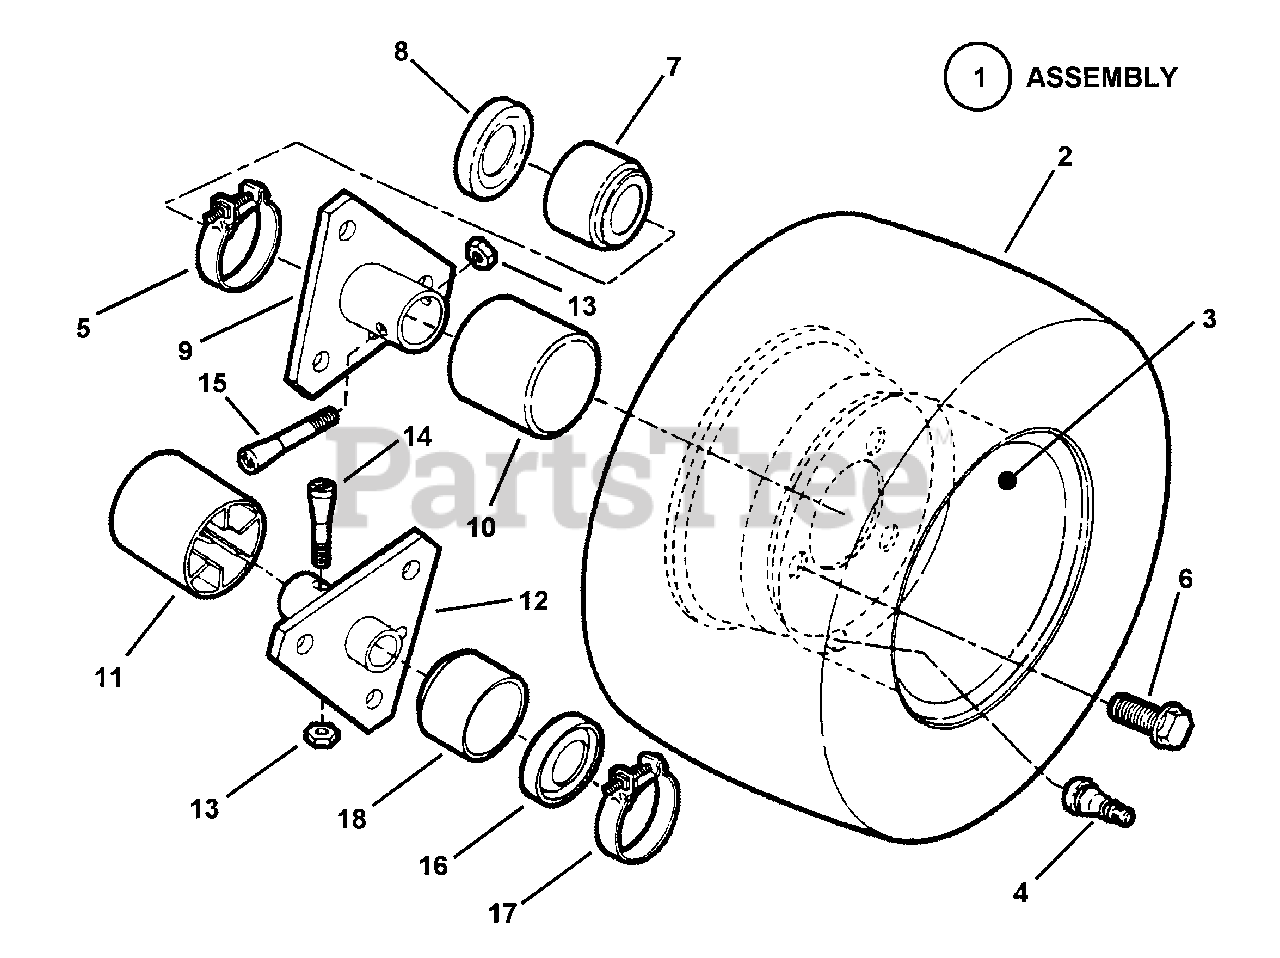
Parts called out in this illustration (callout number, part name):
1	ASSEMBLY, Rear Tire & Rim
2	TIRE, 16 x 6.50-8 (Kenda)
3	RIM, Ext. Wide,
4	VALVE, Air (Snap-in)
5	CLAMP, Right Hand (3.0" ID) (Right Hand)
6	BOLT, 1 /2-20 x 3/4" Lug (Grade 5)
7	CAP, Seal .93" ID x 2.625" OD (Right Hand)
8	SEAL, Oil 1.22" ID x 1.875" OD (Right Hand)
9	HUB, Wheel RH, 3 Hole 1" ID
10	CAP, Hub
11	CAP, Hub (Left Hand)
12	HUB, Wheel LH, 3 Hole 3/4" ID
13	NUT, 5/16-24 Hex Center Lock
14	BOLT, 5/16-24 x 1-5/8" Tapered (Left Hand)
15	BOLT, 5/16-24 x 2" Tapered (Right Hand)
16	SEAL, OIL .750" ID x 1.832" OD (Left Hand)
17	CLAMP, Boot, 2" (Left Hand)
18	CAP, Seal .750" ID x 1.875" OD (Left Hand)
